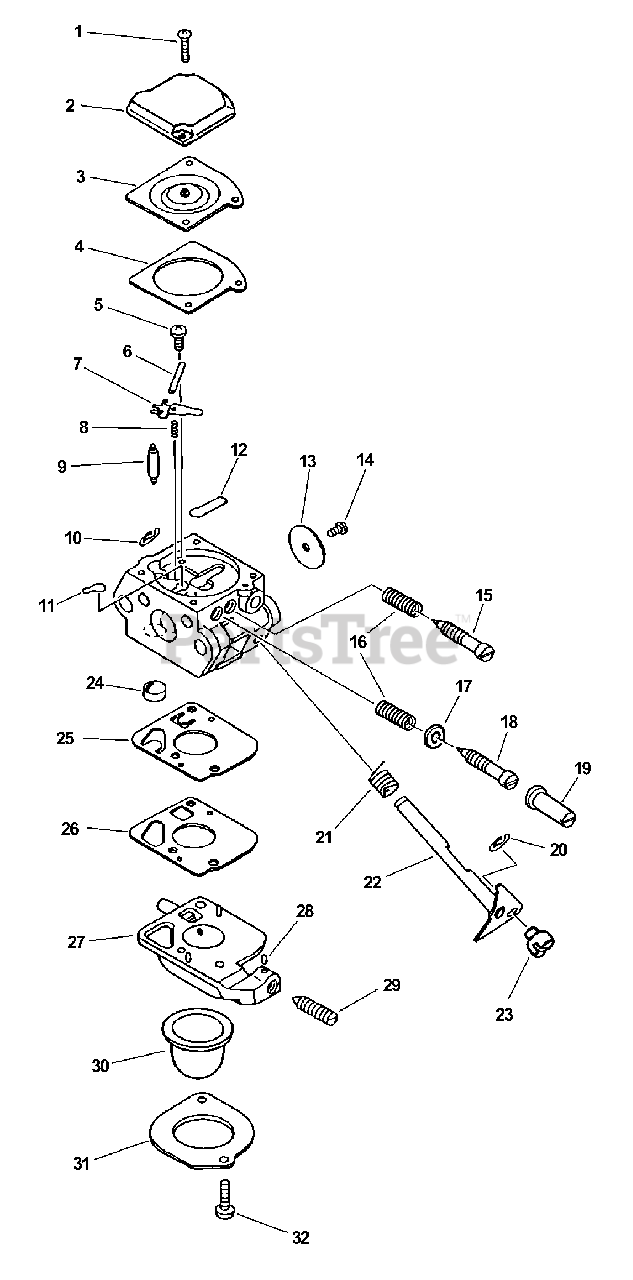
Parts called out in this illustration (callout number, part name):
2	COVER, METERING DIAPHRAGM
3	DIAPHRAGM
4	GASKET, METERING
6	PIN, METERING LEVER
7	LEVER, METERING
9	VALVE, NEEDLE
11	PLUG, WELCH
12	PLUG, WELCH
13	VALVE, THROTTLE
15	NEEDLE, IDLE
16	SPRING, NEEDLE
18	NEEDLE, HIGH SPEED
19	CAP, LIMITER
21	SPRING, THROTTLE RETURN
22	SHAFT, THROTTLE
24	STRAINER
27	BODY ASSY, PURGE
28	PIECE, FRICTION
29	SCREW, IDLE ADJUST
30	BULB, PURGE
31	RETAINER
32	REPAIR KIT
32	GASKET / DIAPHRAGM KIT
